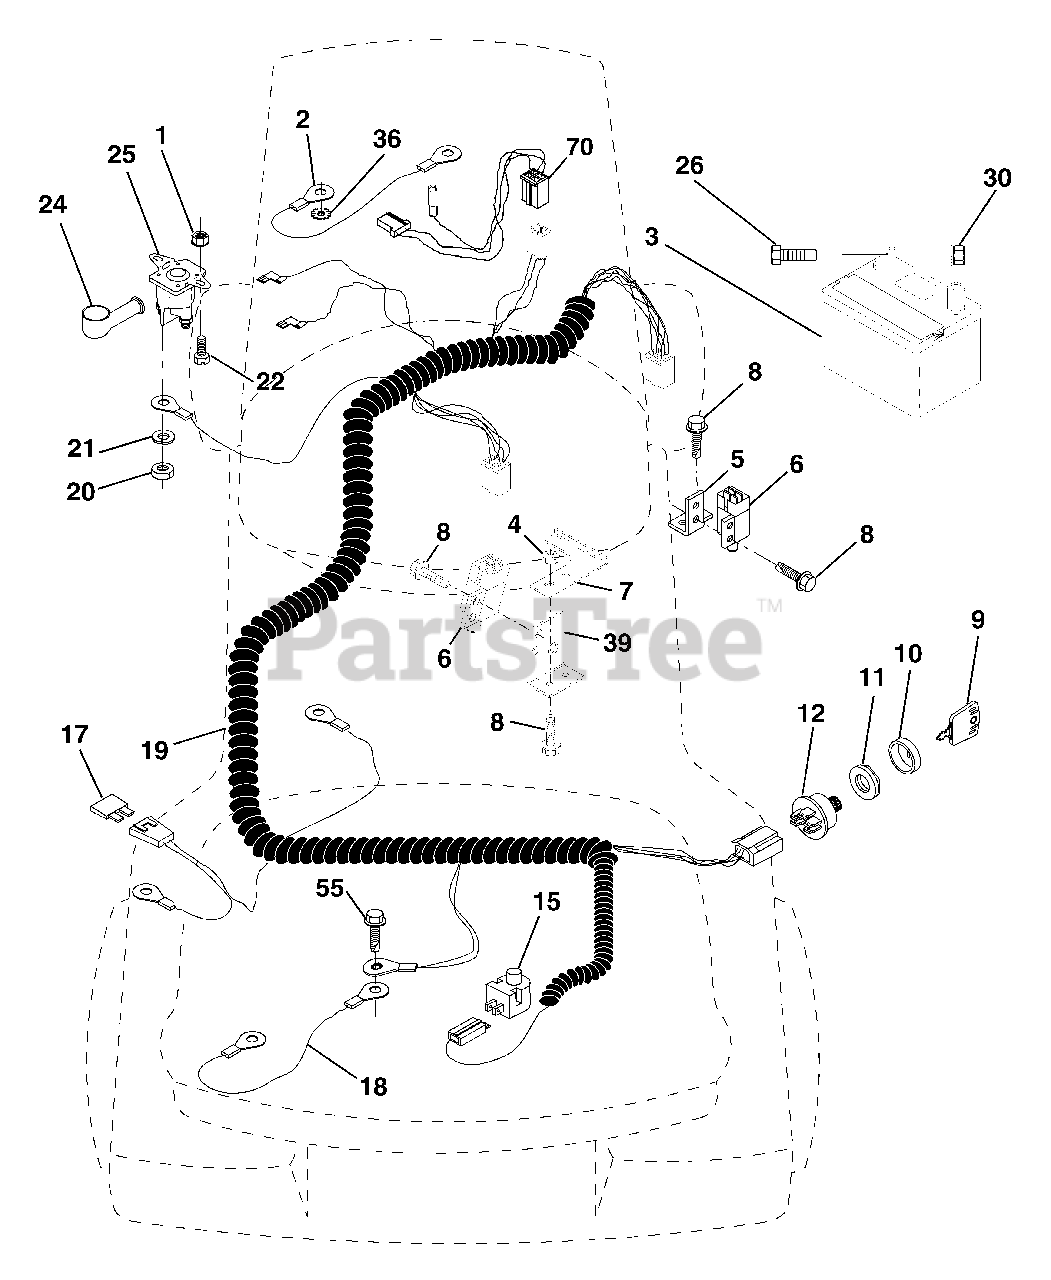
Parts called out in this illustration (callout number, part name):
1	Nut, Hex Keps 1/4-20
2	Assembly, Cable
3	Battery
4	Nut, Lock #10-24 Unc
5	Bracket, Switch
6	Switch, Interlock (4-terminal)
7	Keeper, Actuator
8	Screw, Hex Hd. Tap #10-24 x 1/2
9	Key, Mplded
10	Cover, Key Ignition
11	Nut, Ignition
12	Switch, Ignition
15	Switch, Plunger
18	Assembly, Cable
19	Harness, Ignition
20	Nut, Hex Jam 1/4-20
21	Washer, Lock 1/4
22	Bolt, Fin. Hex 1/4-20 UNC x 1/2
24	Cover, Terminal
25	Solenoid
26	Bolt, Hex Hd. 1/4-20 UNC x 3/4
27	Washer 9/32 x 5/8 x 16
28	Washer, Lock 1/4
30	Nut, Fin. Hex 1/4-20 UNC
36	Washer Lock Inter. Tooth 1/4
39	Bracket Switch Clutch
55	Screw Thdrol 5/16 - 18 x 1/2
70	Harness Engine
